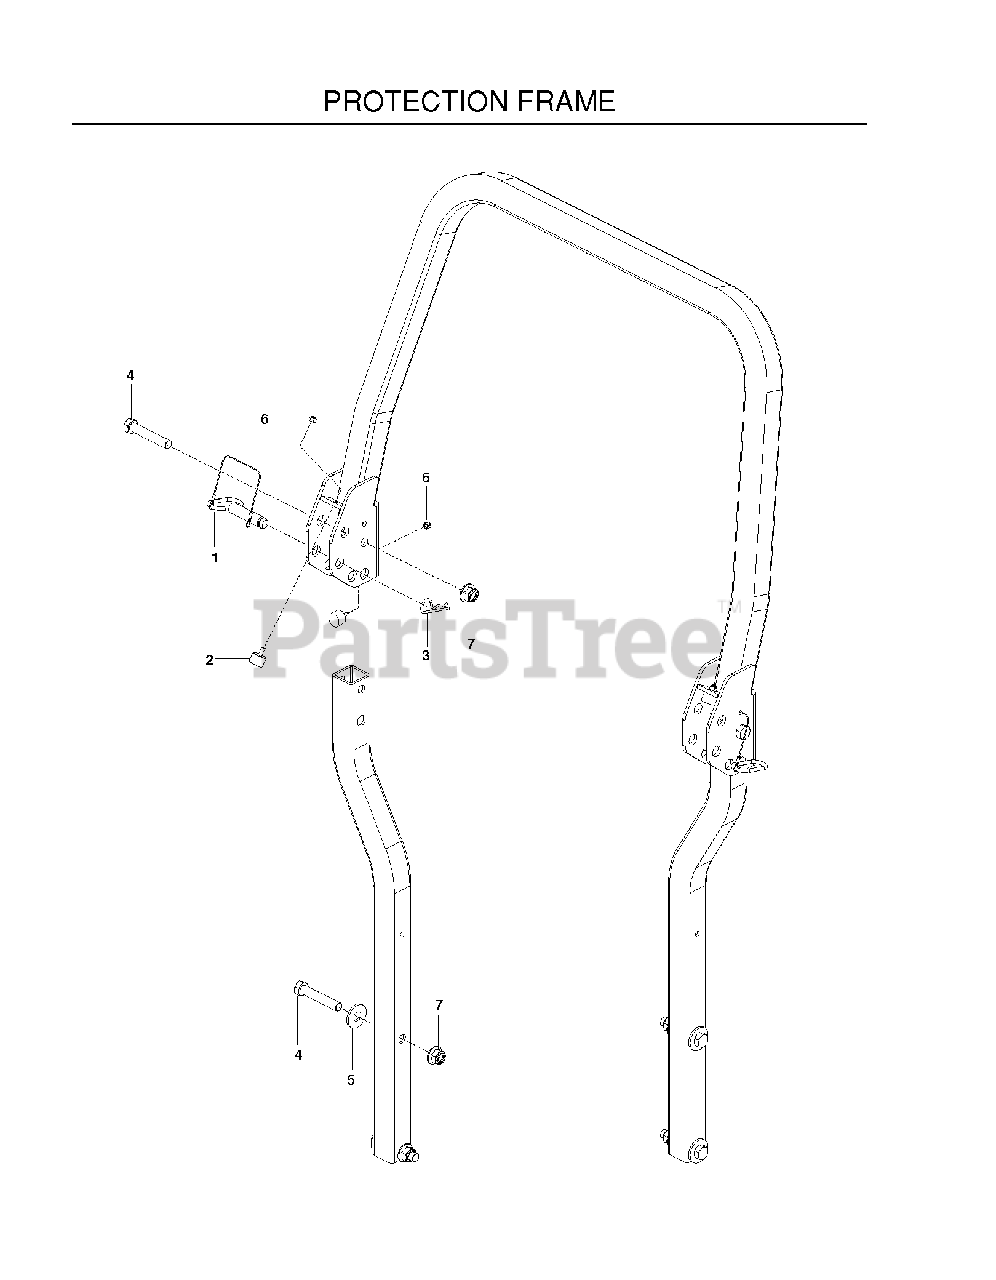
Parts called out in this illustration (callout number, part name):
2	BUMPER, MALE STUD, 1/4-20
3	PIN HAIR .148 X 2-15/16 #210
4	5/8-11 X 3-1/2 HHB GRADE 5
5	WASHER, 5/8 FLAT
6	RP_NUT 1/4-20 NYLOC
7	NUT 5/8-11 FLG NYLOC ZD
